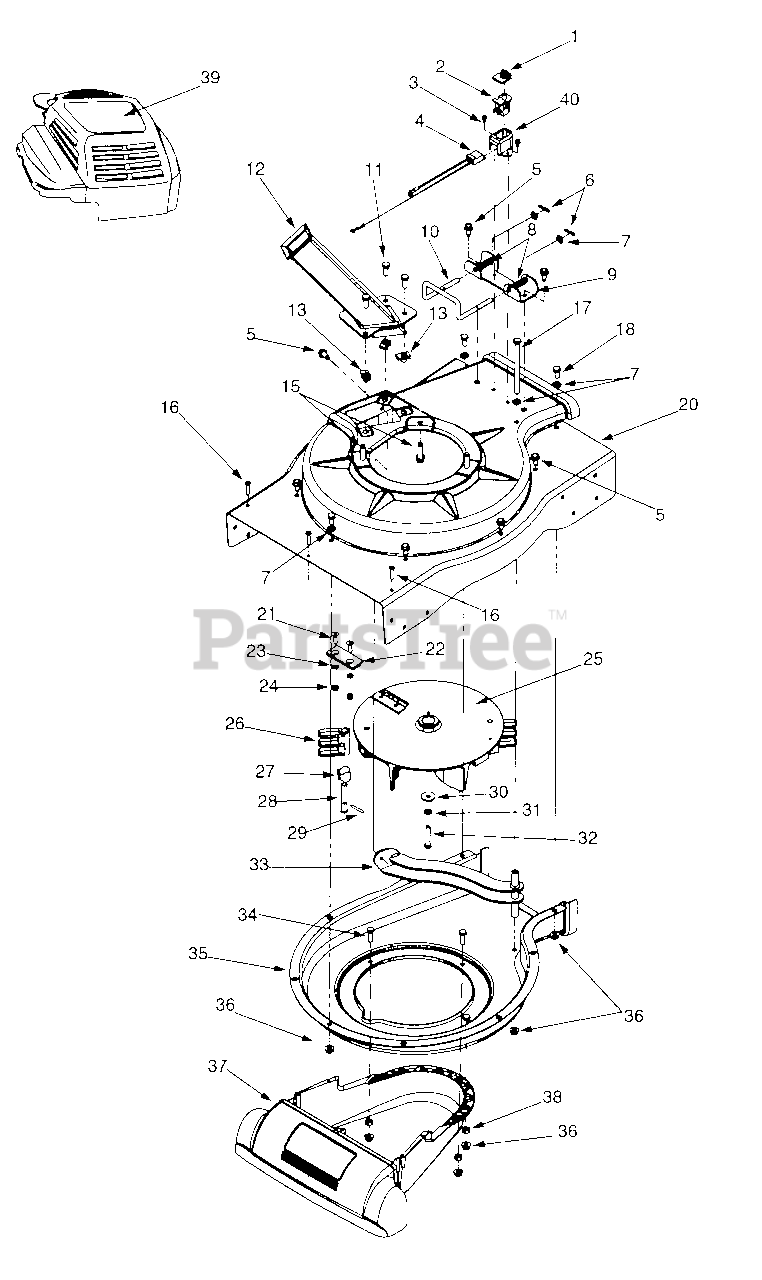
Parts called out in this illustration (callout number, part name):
1	Switch Cover
2	Safety Switch
3	Hex Washer Screw #10-16 x .50
4	Wire Harness
5	Hex Washer Screw 5/16-18 x .625
6	Cotter Pin
7	Flat Washer .330 ID x .630 OD
8	Compression Spring
9	Mounting Bracket
10	Lock Rod
11	Hex Cap Screw 5/16-18 x .75
13	U-Clip Lock Nut 5/16-18
15	Hex Washer Screw 3/8-16 x 1.25
16	Screw #12-16 x 1.0
17	Hex Cap Screw 5/16-18 x 4.5
18	Hex Cap Screw 5/16-18 x .625
22	Chipper Blade
23	Lock Washer 5/16
24	Hex Lock Nut 5/16-24
25	Impeller Ass'y
26	Flail Blade
27	Pin Clip
28	Clevis Pin
29	Spiral Pin
30	Flat Washer 3/8 ID x 1.25 OD
31	Lock Washer 3/8
32	Hex Cap Screw 3/8-24 x 2.0
33	Screen Ass'y
34	Hex Cap Screw 5/16-18 x .875
36	Lock Nut 5/16-18
37	Nozzle Cover
38	Lock Nut 5/16-18
40	Safety Switch Cover
